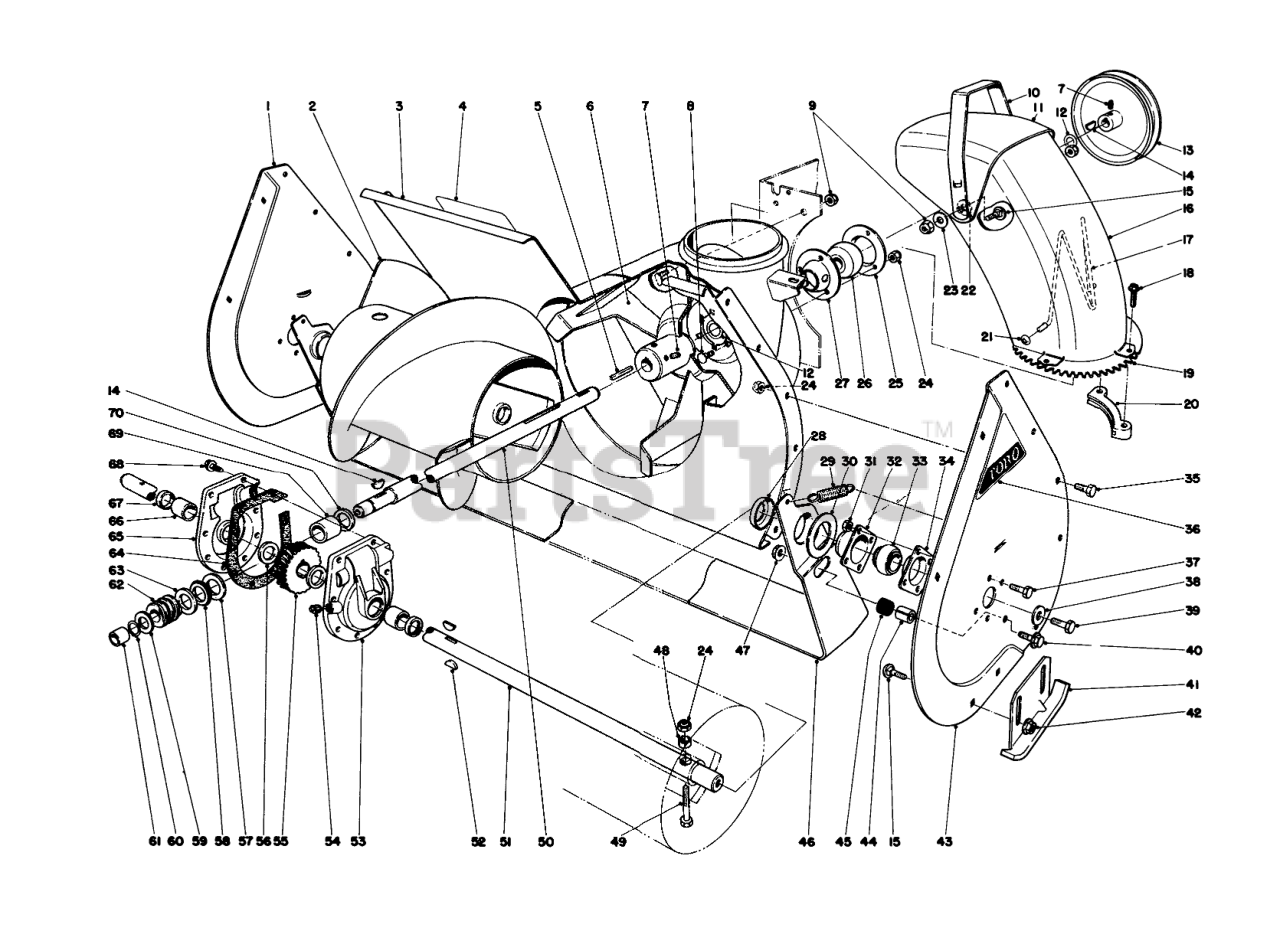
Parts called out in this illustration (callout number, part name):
1	RH AUGER SIDE PLT R
2	Auger Right
3	AUGER HSG WA RO
4	Decal-Warning
6	IMPELLER WA RO
7	SCREW-SET, SQH
8	BOLT-CARR
9	NUT-LOCK, CONE
10	DEFLECTOR HANDLE B
11	Chute Deflector
12	WASHER
13	IMPELLER PULLEY
14	KEY-WOODRUFF
15	SCREW-CARR
16	Chute
17	WIRE-CHUTE
18	SPECIAL SCREW
19	Gear-Chute Swivel
20	CHUTE RETAINER
21	NUT-PUSH
22	WASHER-RUBBER
23	WASHER-BELLEVILLE
24	NUT-LOCK, NI
25	FLANGE-CUP, BEARING
26	Ball Bearing
27	FLANGE-CUP, BEARING
28	Positioner-Scraper
29	SPRING-TENSION
30	SCRAPER BLADE SPACER
32	BEARING-FLANGE, FRONT
33	BEARING
34	BEARING-FLANGE, REAR
35	SCREW-HH
36	AUGER SIDE PLT DECAL
37	SCREW-HH
38	WASHER
39	SCREW-HH
40	SCREW-HHF
41	AUGER SKID WA R
42	NUT-HHF, WHIZ
43	LH AUGER SIDE PLT R
44	SCRAPER STOP SPACER
45	SCRAPER STOP CUSHION
46	24 SCRAPER BLD
47	NUT-HF
48	SPACER-HUB, AUGER
49	Auger Bolt
50	Shaft Impeller
51	24 AUGER SHAFT
52	KEY-WOODRUFF
53	Gear Case (Incl. Ref. #66 & 67)
54	PLUG-PIPE, SQH
55	GEAR-WORM, 27T
56	WASHER-THRUST
57	WASHER-THRUST
58	BEARING-THRUST
59	WASHER-THRUST
60	Ring-Snap
61	BUSHING
63	THRUST-WASHER
64	GASKET-CASE, GEAR
65	Gear Case (Incl. Ref. #66 & 67)
66	BUSHING
67	SEAL-OIL
68	Thread Form Screw
69	BUSHING-SPECIAL
70	RING-QUAD
